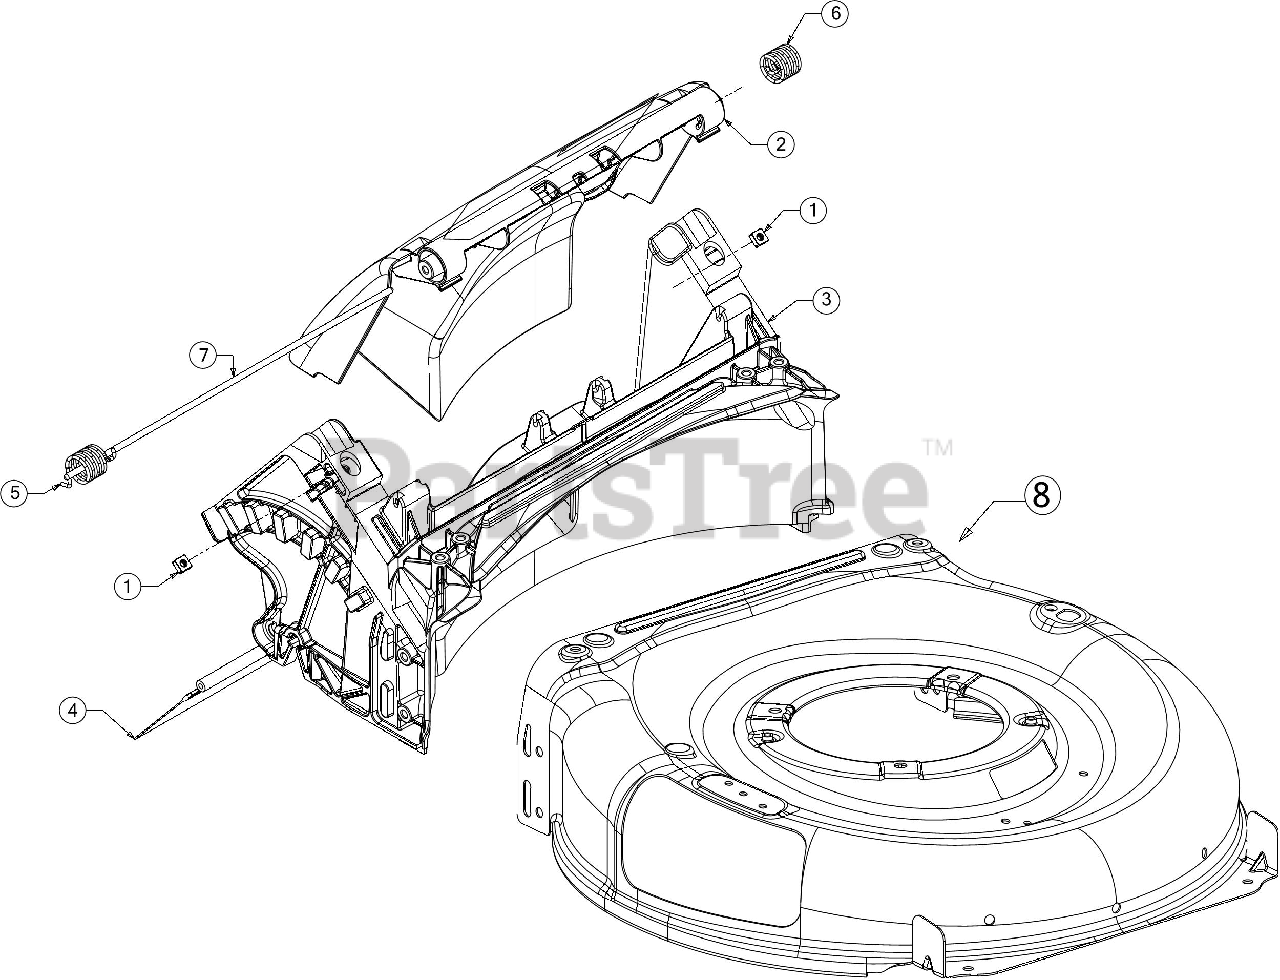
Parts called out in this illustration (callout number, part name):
1	SQUARE NUT 1/4-20
3	DOOR ASSEMBLY
4	TRAILSHIELD
5	TORSION SPRING (RH)
6	TORSION SPRING (LH)
7	REAR DOOR PIVOT ROD
8	21" DECK (3N1)
